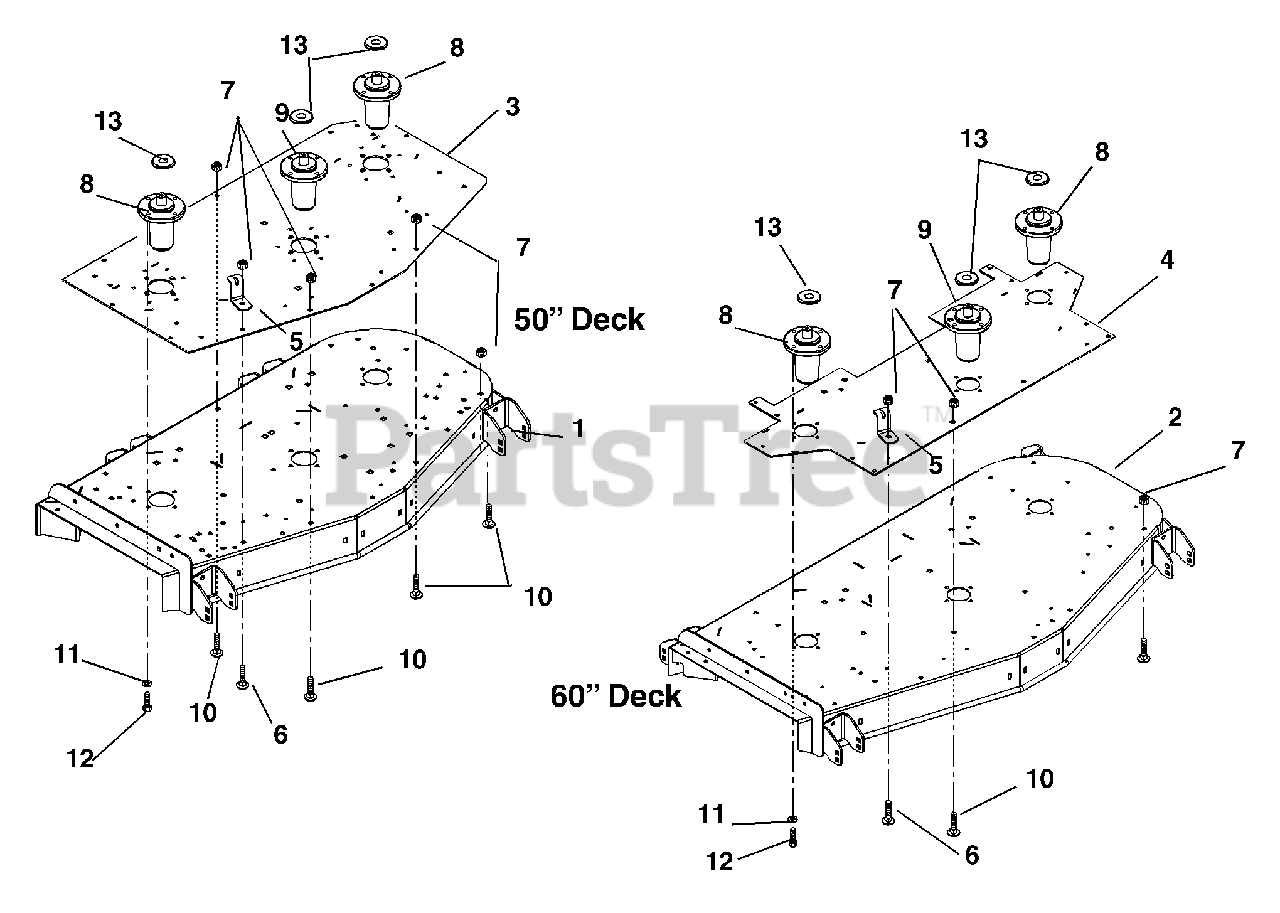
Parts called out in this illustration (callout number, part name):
1	Weldment, 50"Deck (Side Discharge)
2	Weldment, 60" Deck (Side Discharge)
3	Plate, 50" Reinforcement
4	Plate, 60" Reinforcing
5	Anchor, Spring
6	Bolt-Round Head Square Neck .38-16 x 1.25 Grade 2
7	Nut-Locking-Nylon .38-16 (50" Deck)
7	Nut-Locking-Nylon .38-16 (60" Deck)
8	Assembly, Spindle L-Hub
9	Spindle Assembly (Center)
10	Bolt-Round Head Square Neck .38-16 x 1.00 Grade 2 (50" Deck)
10	Bolt-Round Head Square Neck .38-16 x 1.00 Grade 2 (60" Deck)
11	Washer-Locking .38 x .094
12	Bolt-Hex .38-16 x 1.00 Grade 5
13	Slinger-Dust
